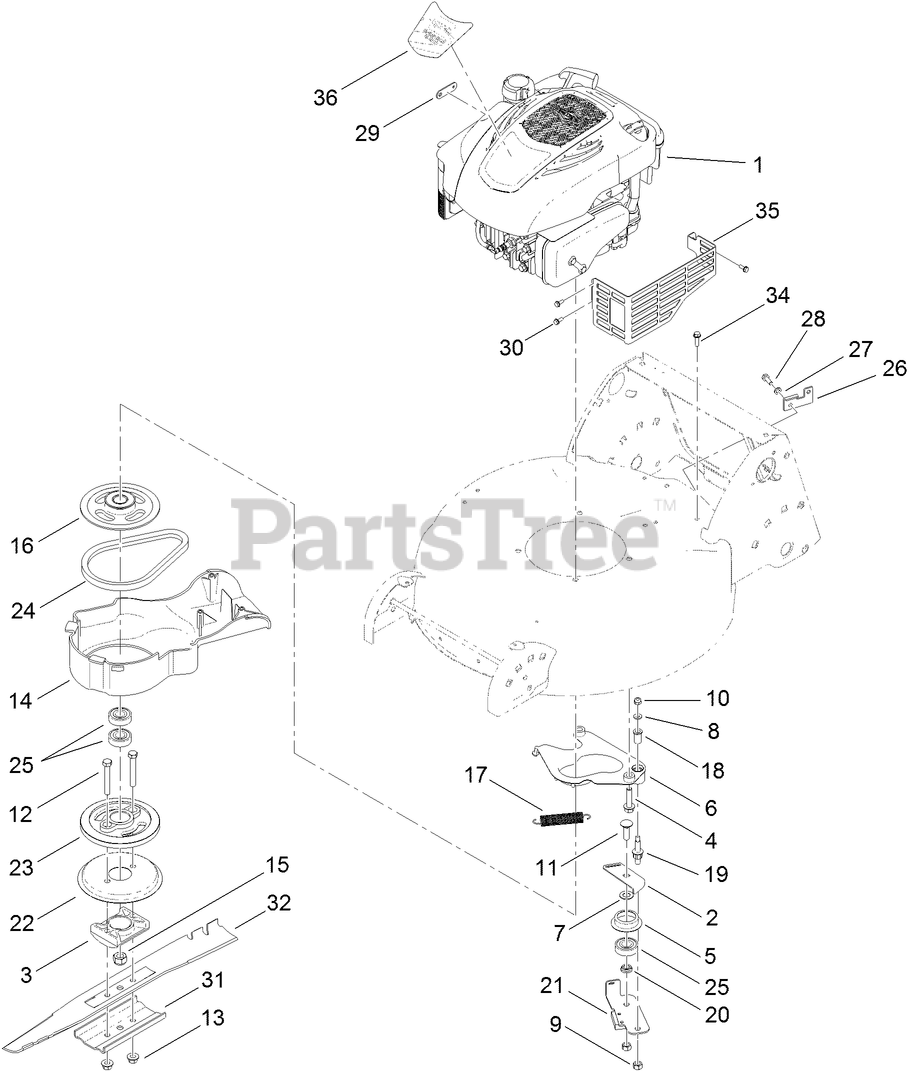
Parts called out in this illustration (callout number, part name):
2	PLATE-GUIDE
3	SUPPORT-BLADE
4	SCREW-HWH
5	RETAINER-BELT
6	PLATE-ANCHOR
7	SPACER
8	WASHER-FLAT
9	LOCKNUT
10	NUT-LOCK, NI
11	BOLT-CARR
12	SCREW-HH
13	NUT-LOCK
14	COVER-BBC
15	NUT-HEX
16	PULLEY
17	SPRING-TENSION, BRAKE
18	BUSHING
19	BOLT-SHOULDER
20	SPACER-BEARING
22	DISC
24	BELT
26	CLAMP-CABLE, BBC
27	WASHER-LOCK
28	SCREW-HH
29	PLATE-TERMINAL
30	SCREW-TAPTITE
31	SUPPORT-BLADE
34	SCREW-HWH
35	SHIELD-MUFFLER
36	DECAL-SHROUD
